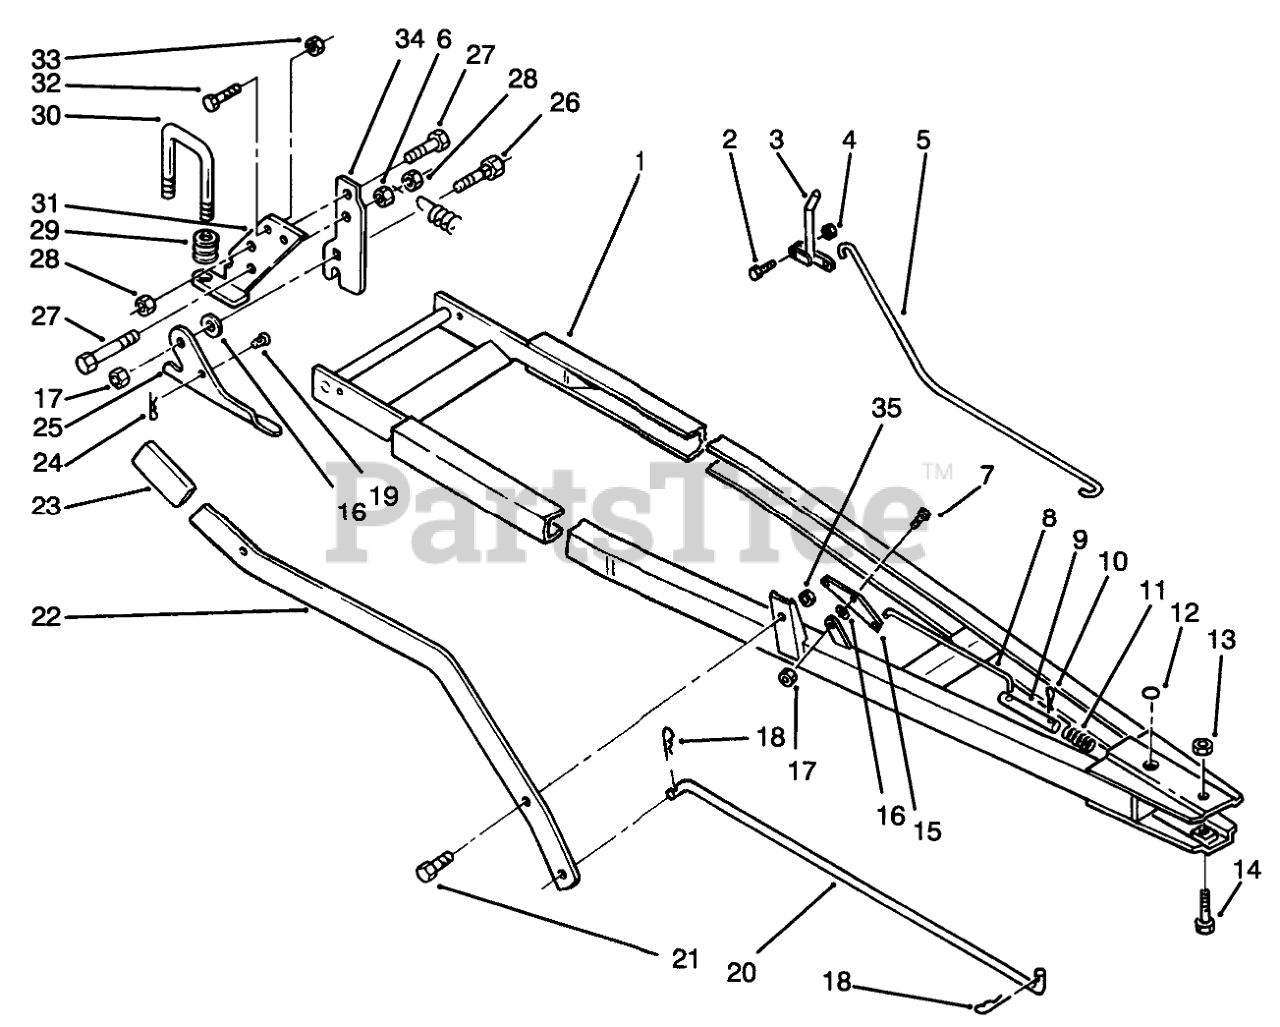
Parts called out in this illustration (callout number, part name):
1	Frame
2	SCREW-HH
3	INDEX LEVER
4	NUT-LOCK
5	ROD-UPPER INDEX
6	Jam Nut
7	SCREW-HH
8	ROD-LOWER INDEX
9	Index Pin
10	PIN-COTTER
11	SPRING-COMPRESSION
12	PLUG
13	Nut
14	SCREW-HH
15	Index Plate
16	WASHER-FLAT
17	NUT-LOCK, NI
18	Hairpin
19	Pin
21	EYEBOLT
22	LEVER-BLADE CONTR R
23	GRIP
24	Hairpin
25	PLATE-LATCHING
26	BOLT-CARR
27	H H C S
28	NUT-LOCK, NI
29	Washer
30	U-BOLT
31	PLATE-HITCH
32	SCREW-HH
33	NUT-LOCK, NI
34	BRACKET-HITCH
35	Nut
36	SCREW-HH
